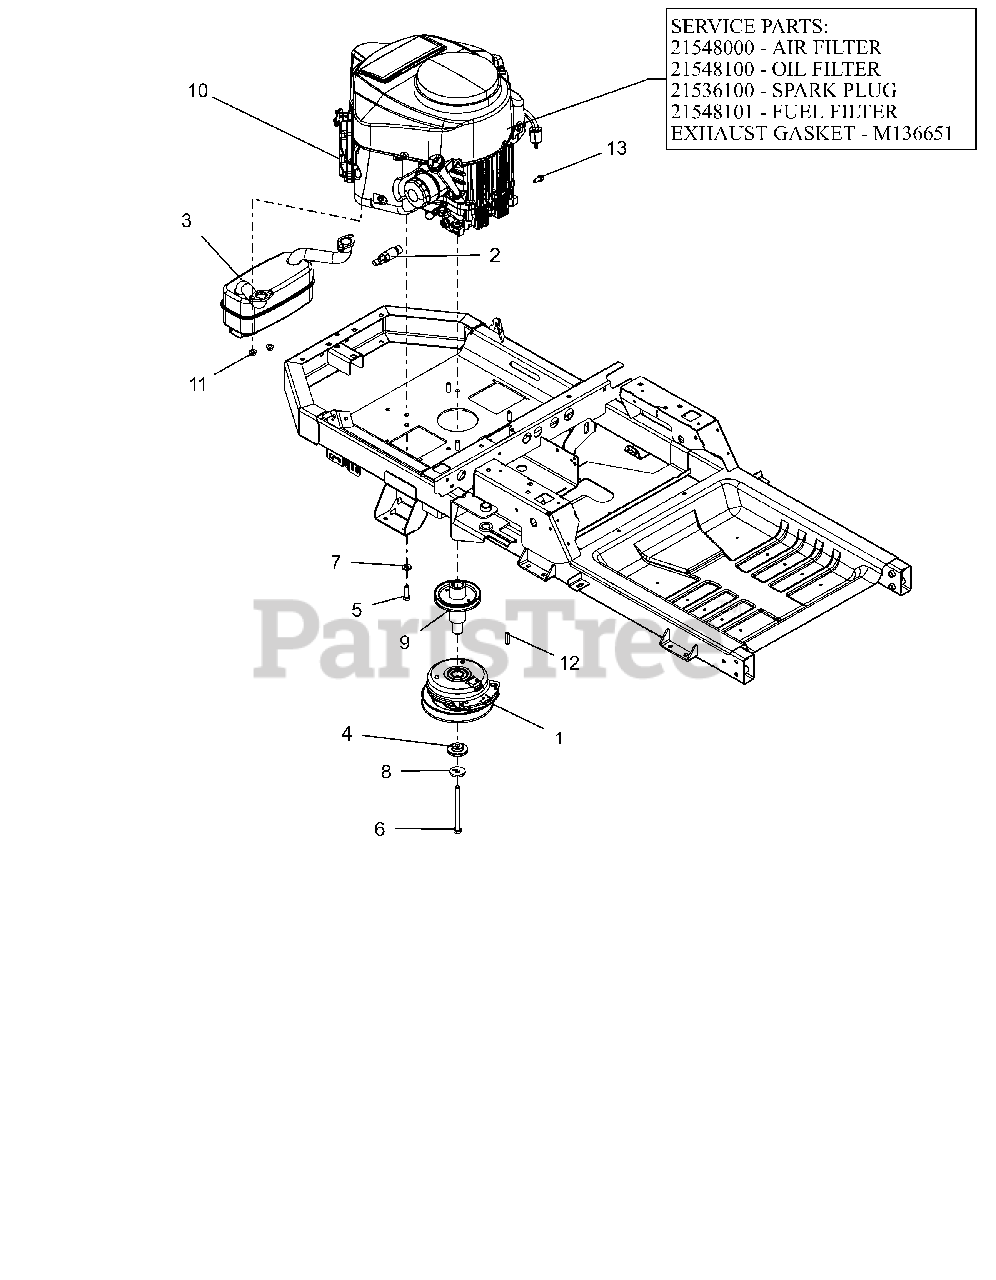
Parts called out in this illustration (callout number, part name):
1	CLUTCH,105FTLB MONOPOLE 6.83"
2	DRAIN, OIL M20X2.5
3	MUFFLER - KAWASAKI
4	BSHG-FLG .469X1.06X.574X2.0
5	BLT, HEX .38-16X1.25 G5 ZCC NT
6	BLT-HEX.438-20X5 GR8 YZ NYTORQ
7	WASHER, 3/8" SPRING DISC
8	WASHER, 7/16" SPRING DISK
9	WLDMT, DRIVE SHEAVE (LG XL)CZC
10	ENGINE, KAWASAKI FR691 23HP
10	AIR FILTER, KAWASAKI FR
10	OIL FILTER, KAWASAKI FR
10	PLUG, SPARK
10	FUEL FILTER-KAWASAKI FR
10	GASKET, MUFFLER #
11	NUT-LK-TOP-FLG M8 ZCC
12	KEY-SQ .25 X 1.25 X .25 SAE
13	BLT, HEX M8-1.25X20 G8.8 ZCC
